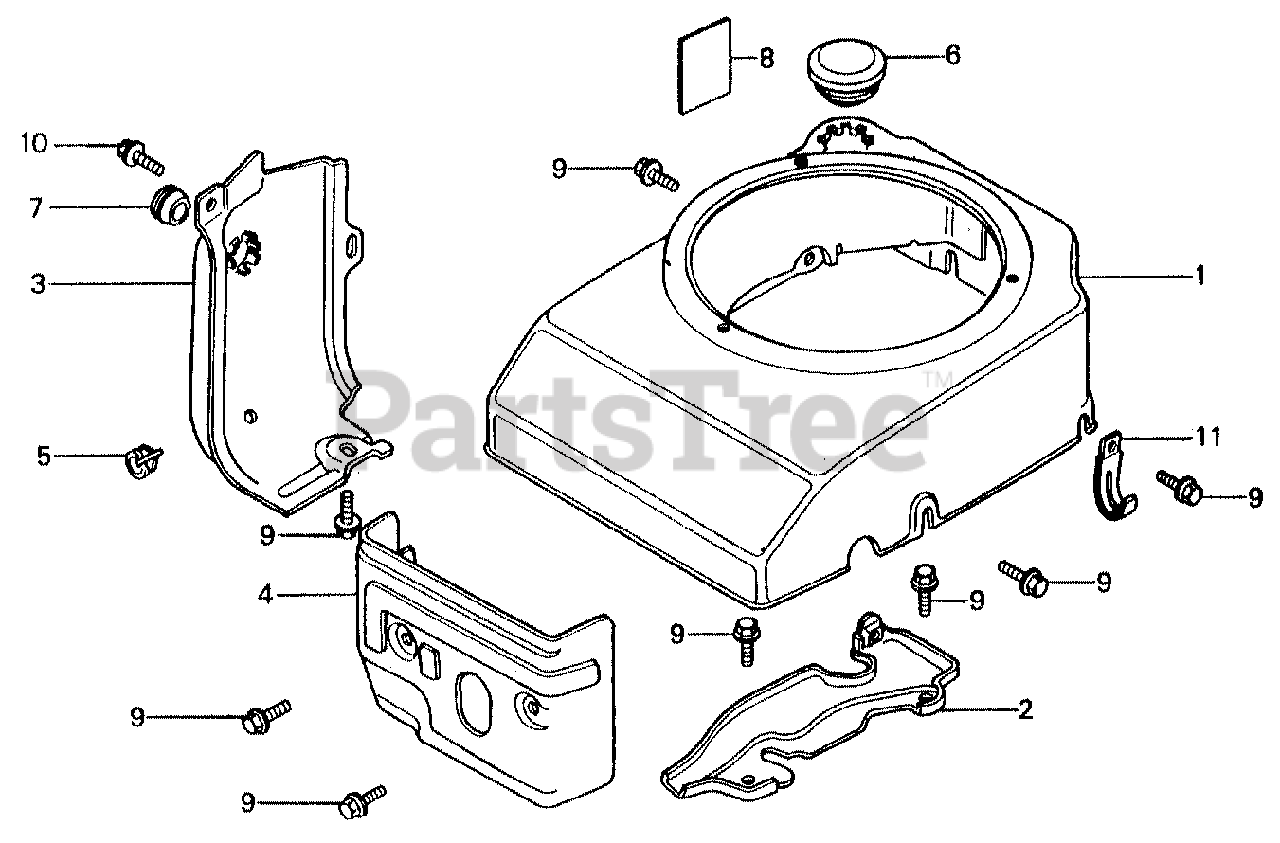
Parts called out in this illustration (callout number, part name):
1	COVER, FAN *R8* (BRIGHT RED)
1	COVER, FAN *NH67* (SPARKLE WHITE)
2	PLATE, SIDE
3	SHROUD
4	COVER, TOP
5	CLIP, IGNITION WIRE (8MM)
6	GROMMET B, SIDE PANEL
7	GROMMET, DRAIN HOLE
8	MARK, OIL CAUTION
9	BOLT, FLANGE (6X12) (CT200)
10	BOLT, FLANGE (6X14)
11	CLIP, CABLE
